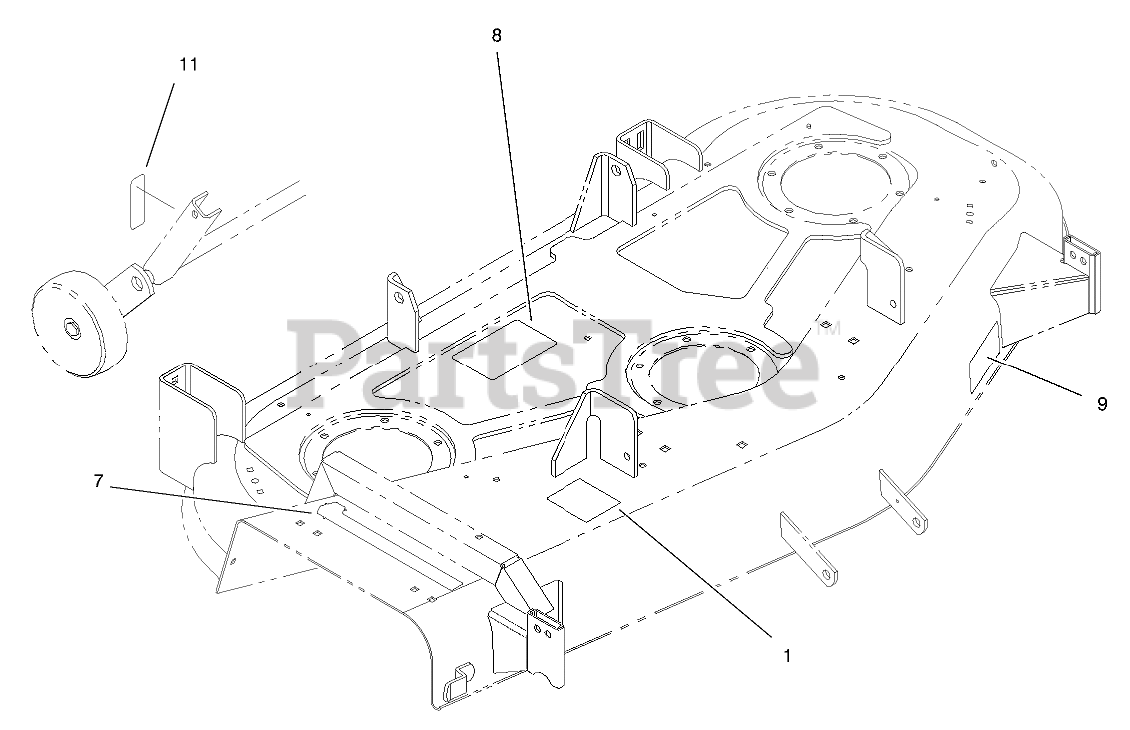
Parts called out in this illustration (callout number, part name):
1	DECAL-BELT ROUTING
7	Decal-Deck (Only On: 78375)
8	DECAL-BELT ROUTING
9	DECAL-ADJUSTMENT, WHEEL
11	Decal-Height Of Cut (Only On: 78370, 78375)
